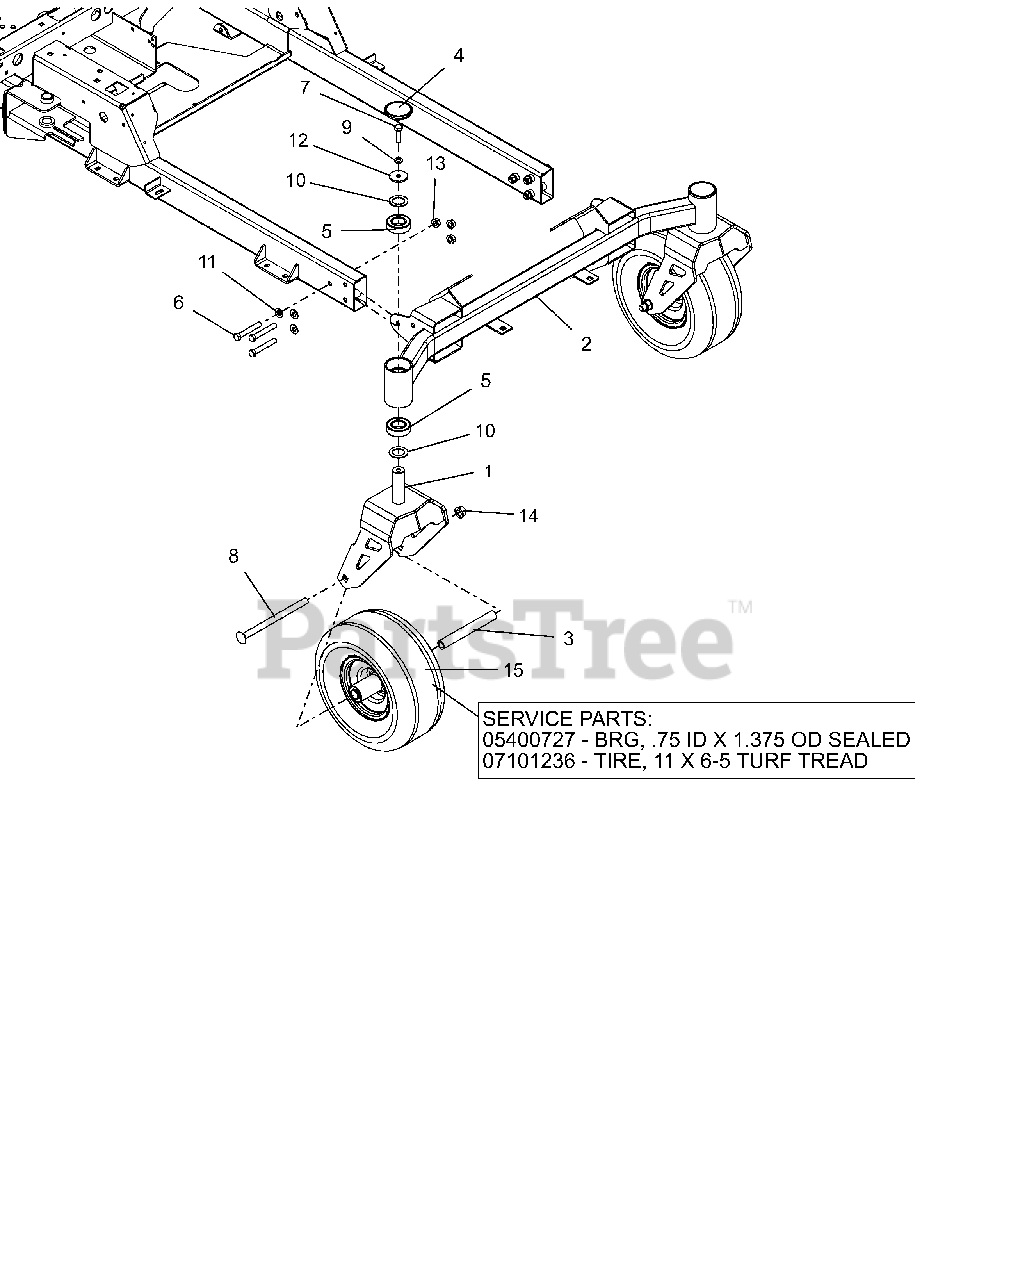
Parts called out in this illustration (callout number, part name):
1	WLDMT, CASTER FORK (WIDE)
2	WLDMT, AXLE FRONT
3	SPACER, FRONT WHEEL (WIDE 6.0)
4	CAP, DUST
5	BRG,BALL 1.00X2.00X.563(1641)
6	BLT-HEX .38-16X2.50 GR8 YWZC
7	@BLT-HEX .38-16X1.25 GR5 YWZC
8	@BLT-RDHDSQNK .50-13X7.50 G5YZ
9	@WSHR-LK .38X.094 REG YWZC
10	WSHR-HRD-THRS 1.007X1.542X.062
11	WSHR-HDND .406X.812X.055
12	WSHR-FL-STL .380X1.50X.125YWZC
13	NUT-LK-TOP-FLG .38-16 GRG YWZC
14	@NUT-LK-TOP-FLG .50-13 YWZC
15	TIRE/WHEEL ASSY, 11X6-5
15	BRG, .75 ID X 1.375 OD SEALED
15	TIRE, 11X6-5 TURF TREAD
